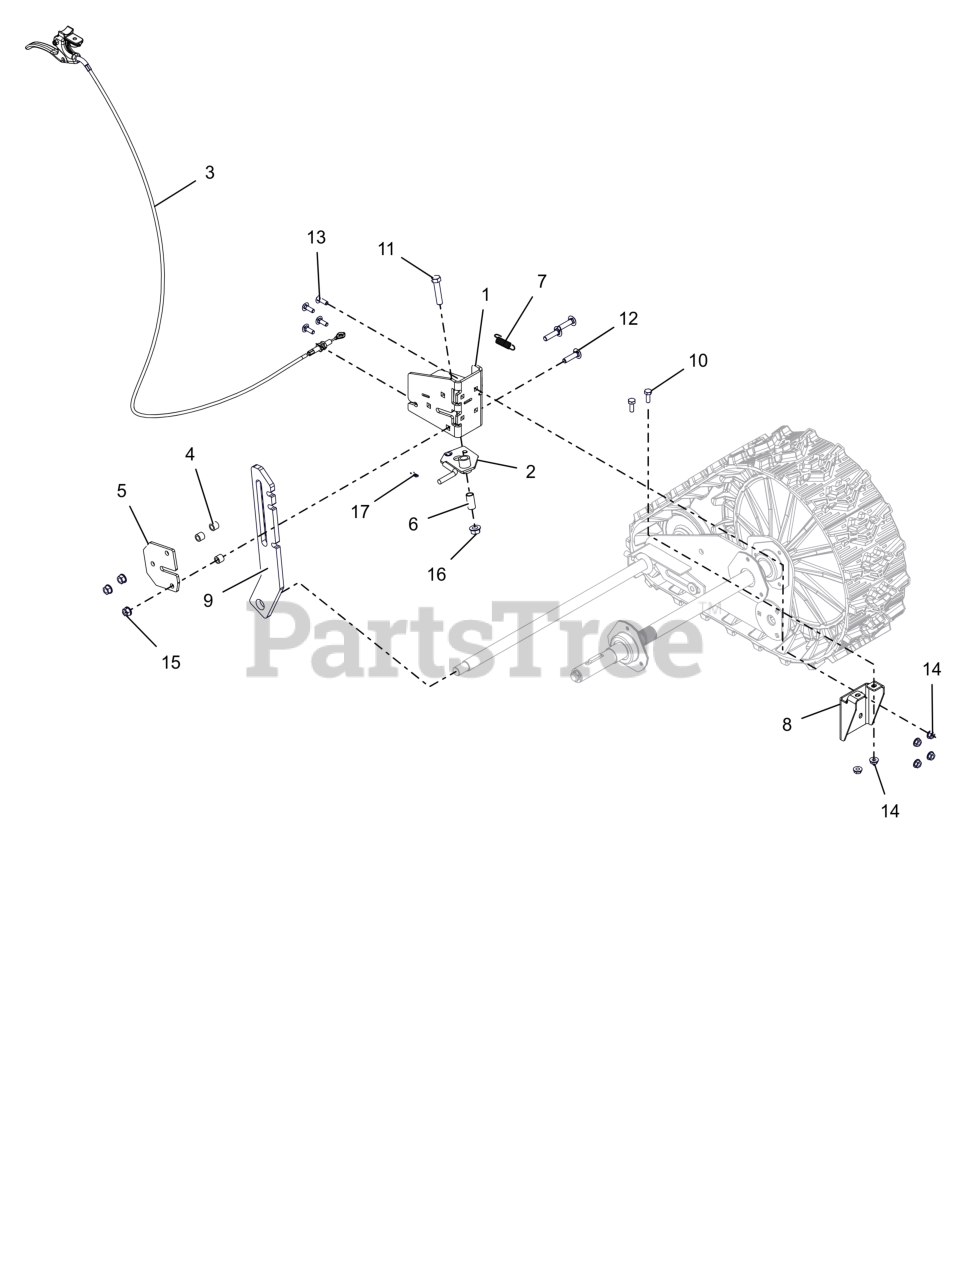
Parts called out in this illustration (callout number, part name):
1	BRACKET,HEIGHT ADJUSTER-DELUXE
2	LOCK,HEIGHT ADJUSTER TRIGGER
3	CABLE, TRACK REMOTE
4	SPACER .50 X .32 X .42
5	PLATE, HEIGHT ADJUSTER
6	BSHG-SLV .385X.500X1.045
7	SPRING-EXT .047 X .438 X 1.85
8	BRACKET, REINFORCEMENT
9	ADJUSTER, HEIGHT-DELUXE BWT
10	BLT, HEX .25-20X.75 G5 ZCC
11	BLT, HEX .38-16X1.75 G5 ZCC
12	BLT, RHSSN.31-18X1.25 G5 ZCC
13	BLT, RHSN .25-20X.750 G5 ZCC
14	NUT-LK-CTR-FLG .25-20 ZC120
15	NUT-LK-TOP-FLG .312-18 GF ZCC
16	NUT-LK-CTR-FLG .375-16 GF ZCC
17	PIN, HAIR #178 .06X.77 ZCC
